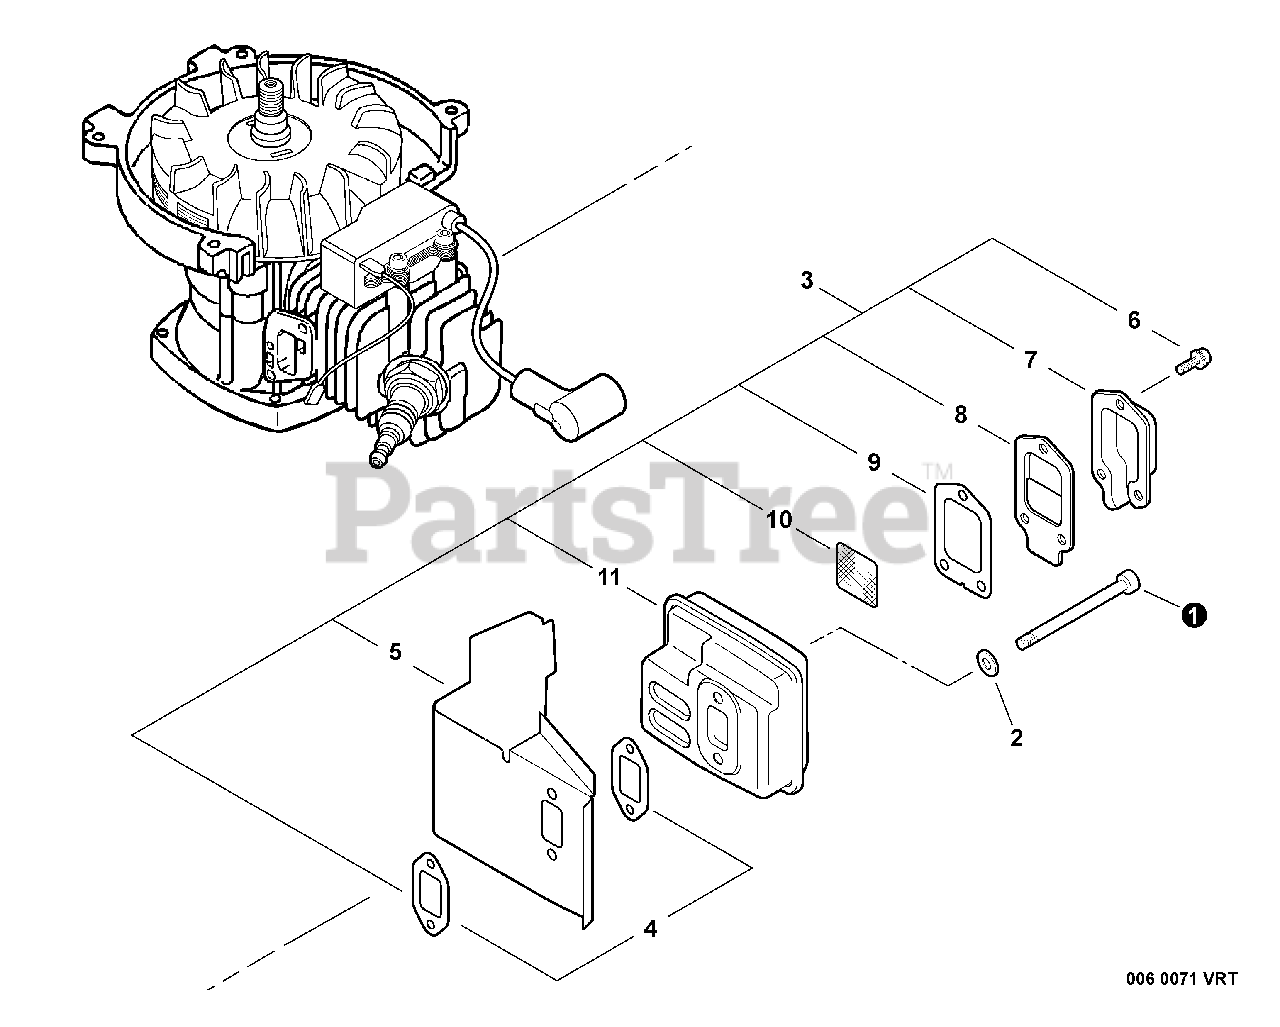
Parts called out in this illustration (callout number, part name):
1	BOLT M5×50
2	WASHER, FLAT 5.5×10×0.8
3	MUFFLER ASSY
4	GASKET, EXHAUST
5	COVER, MUFFLER
6	SCREW 4×10
7	GUIDE, EXHAUST - INNER
8	GUIDE, EXHAUST
9	GASKET, EXHAUST
10	SCREEN, SPARK ARRESTER
